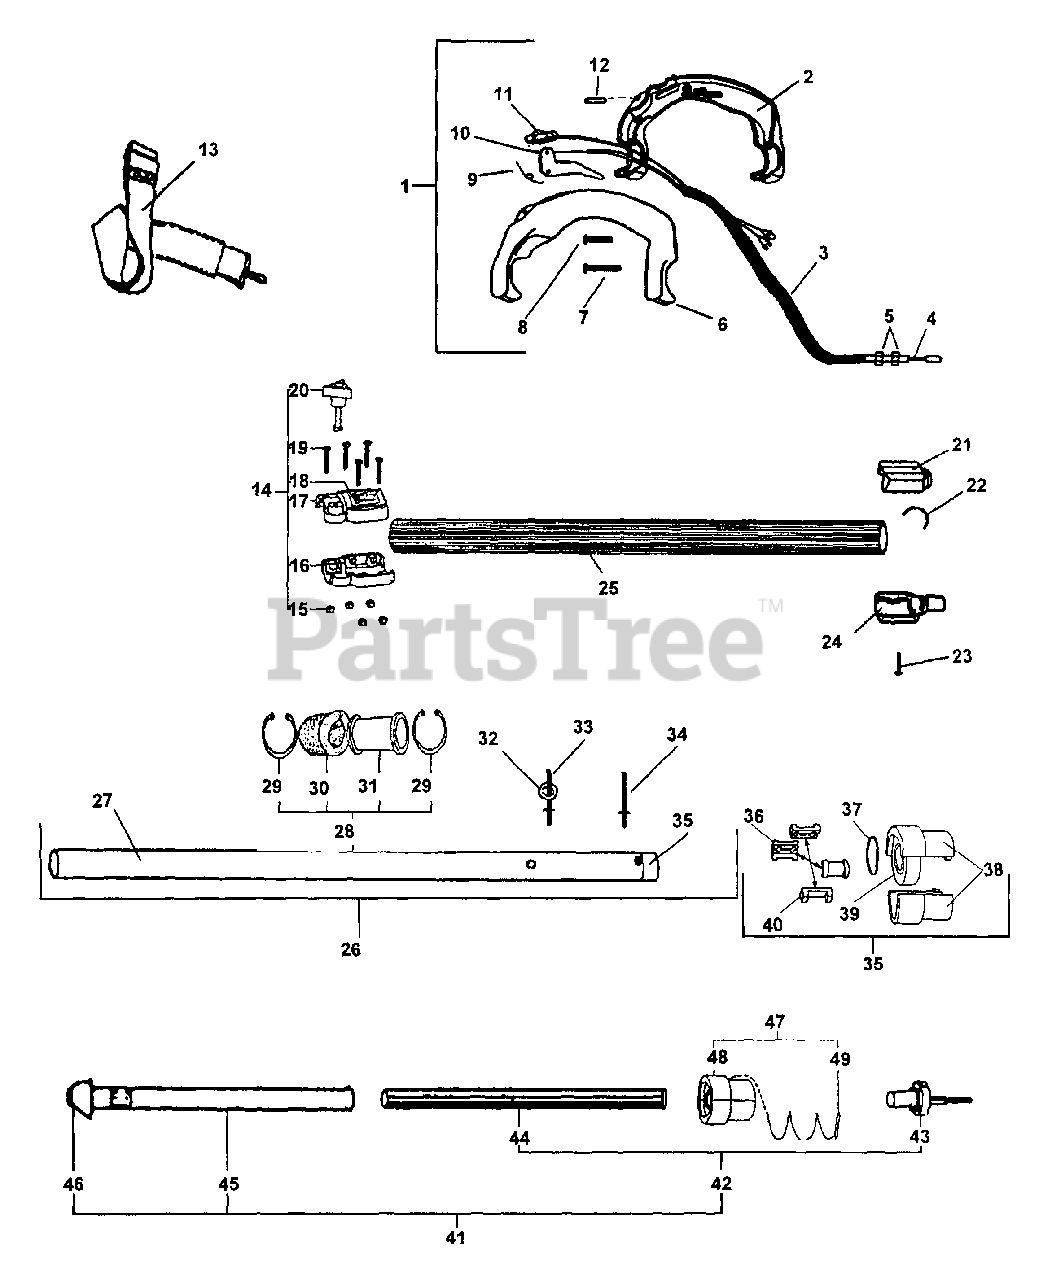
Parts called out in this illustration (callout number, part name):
1	HANDLE ASSY, REAR
2	HANDLE, REAR - RIGHT
3	TUBE, FLEXIBLE
4	CABLE, THROTTLE
6	HANDLE, REAR - LEFT
7	SCREW, TORX 10-24 UNC 1-1/4
8	SCREW, TORX
9	SPRING, TORSION
10	TRIGGER, THROTTLE
11	IGNITION SWITCH ASSY
12	PIN, LOCATING 0.17 OD×0.75 L
13	STRAP ASSY, SHOULDER
14	CLAMP ASSY
15	NUT, LOCK 10-24 UNC
16	COLLAR, LOWER
17	COLLAR, UPPER
18	LABEL - CAUTION
19	SCREW, TORX 10-24 UNC 1-1/4
20	THUMBSCREW
21	CAP, MAIN PIPE
23	SCREW, TORX 10-24 UNC 1-1/4
24	COUPLING, MAIN PIPE
25	PIPE, MAIN 1.5 ID×60" L
26	PIPE, MAIN
27	PIPE, MAIN - BLACK
28	DRIVESHAFT GUIDE ASSY
29	RING, SNAP
30	PAD, FOAM
31	GUIDE, DRIVESHAFT
32	WASHER, FLAT 5
35	HOLDER ASSY, BEARING
36	GUIDE, SHAFT - SMALL
37	WASHER, WAVE
38	HOLDER, BEARING
39	BEARING, BALL 6002 DDU
40	GUIDE, SHAFT - LARGE
41	DRIVESHAFT ASSY
42	DRIVESHAFT - LOWER
43	CONNECTOR, SHAFT
44	DRIVESHAFT
45	SHAFT, UPPER DRIVE L= 79.75
46	ADAPTER, UPPER DRIVE SHAFT
47	BUSHING ASSY, FLOATING
48	BUSHING, FLOATING
49	SPRING, COMPRESSION
